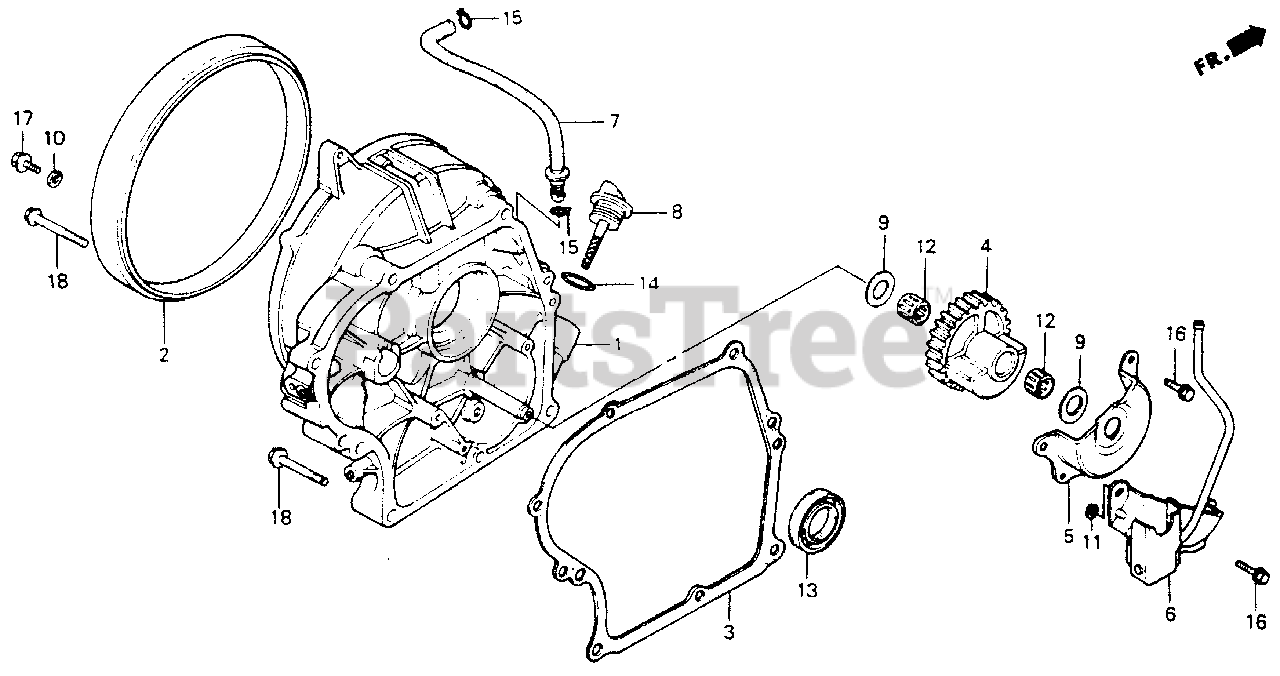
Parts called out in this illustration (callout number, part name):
1	COVER, CRANKCASE (NOT AVAILABLE)
2	RING, SPACER
3	GASKET, CASE COVER
4	WEIGHT, BALANCER
5	COVER, BALANCER
7	TUBE, OIL ALERT
8	CAP, OIL FILLER
9	WASHER, THRUST (15MM)
10	WASHER A (8MM)
11	WASHER, CRANK ARM
12	BEARING, NEEDLE
13	OIL SEAL (30X46X8)
14	O-RING (26X2.7)
15	CLIP, TUBE (C11)
16	BOLT, FLANGE (6X16)
17	BOLT, FLANGE (8X10)
18	BOLT, FLANGE (8X45)
